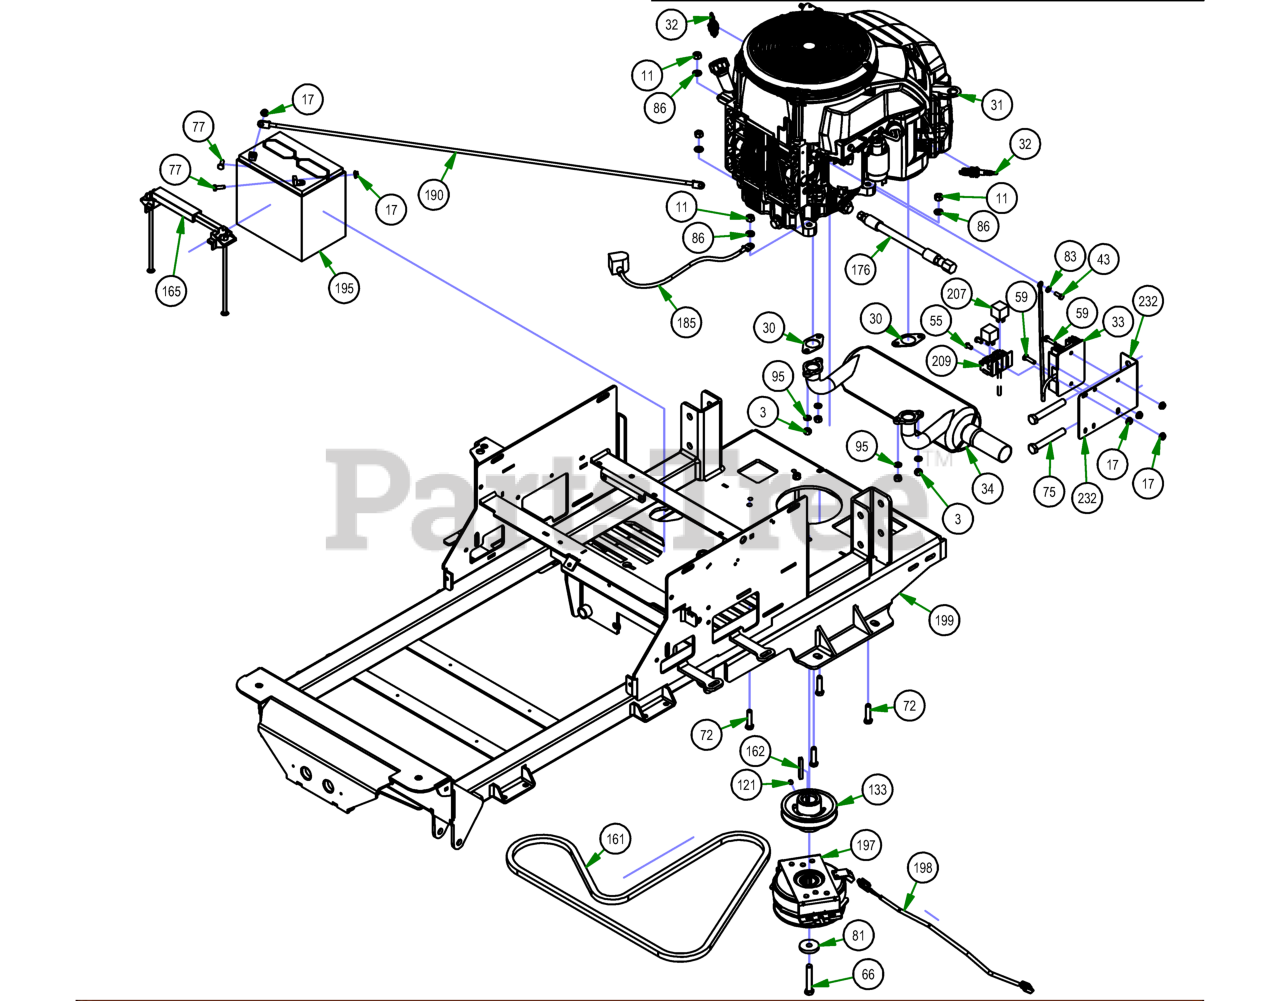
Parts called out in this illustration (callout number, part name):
2	1/2-13 HEX 2-WAY REVERSIBLE CENTER LOCKNUT Grade B ZINC
3	M8-1.25 DIN 934 HEX NUT (CL.8) ZINC
11	3/8-16 HEX NUT ZINC
14	5/16-18 HEX NUT ZINC
17	1/4-20 HEX SERRATED FLANGE NUT HARD/ZINC
30	Exhaust Gasket
31	2019 Honda Engine
32	Spark Plug
33	Regulator Rectifier for Honda Engine
34	2019 Honda Maverick Muffler
43	M6-1.0 X 16MM DIN 933 HEX TAP BOLT (CL 8.8) ZINC
55	1/4-20 X 1/2 BUTTON SOCKET CAP SCREW 18-8 STAINLESS STEEL
59	1/4-20 X 1 HEX CAP SCREW (GR.5) ZINC
66	7/16-20 X 2-1/2 HEX CAP SCREW (GR.8) ZINC YELLOW
70	5/16-18 X 5-1/2 HEX CAP SCREW (GR.5) ZINC
72	3/8-16 X 1-1/2 HEX CAP SCREW (GR.5) ZINC
75	1/2-13 X 3-1/2 HEX CAP SCREW (GR.5) ZINC
77	1/4-20 X 3/4 HEX CAP SCREW (GR.5) ZINC
81	CLUTCH WASHER
83	1/4 SPLIT LOCKWASHER ZINC
86	3/8 SPLIT LOCKWASHER ZINC
95	5/16 SPLIT LOCKWASHER ZINC
121	5/16-24 X 1/4 SOCKET SET SCREW (CUP PT) PLAIN
133	4 3/4 Motor Pulley
161	75.8" Pump Belt
162	1/4 X 2 SQ MACHINERY KEY 1018 STL PLAIN
165	Hold Down Assembly
176	2019 Honda Oil Drain
185	24 inch Black Cable – MZ/ZT
190	36" Red Battery Cable
195	SP-35 Battery
198	Clutch Pigtail
199	2021 Maverick Frame - Painted
207	Relay Terminal
209	Wiring Harness
213	Patent Decal
232	Honda Rectifier Mount
